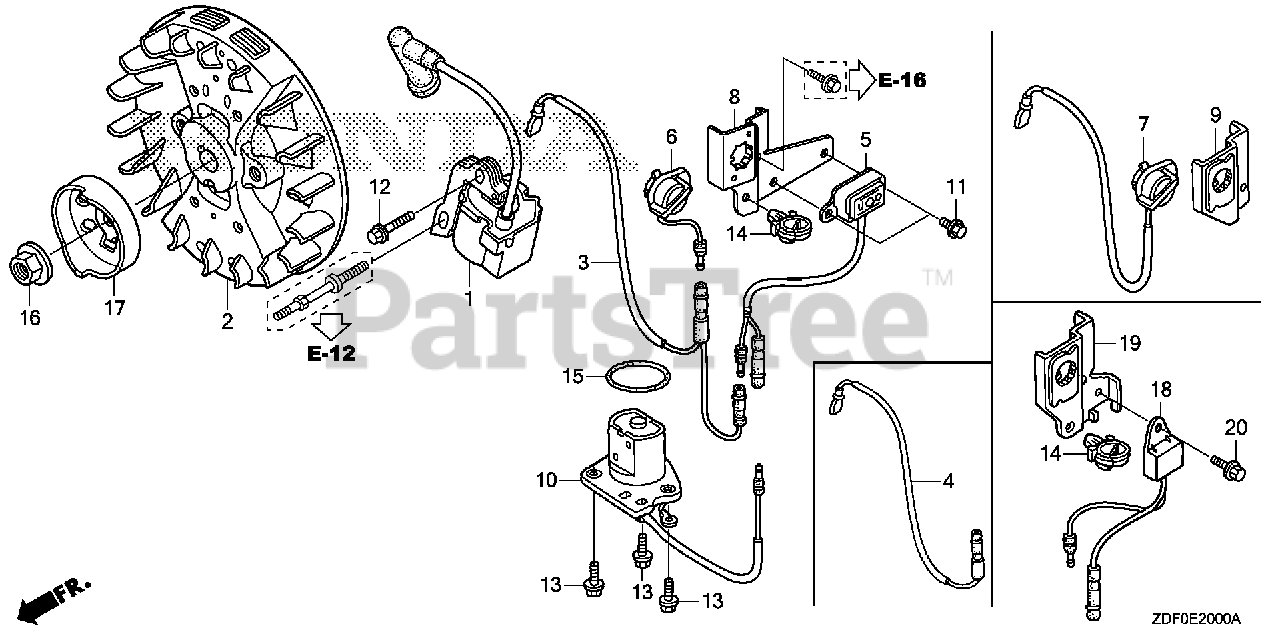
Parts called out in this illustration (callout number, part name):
1	COIL ASSY., IGNITION
3	WIRE, STOP SWITCH
6	SWITCH ASSY., ENGINE STOP
6	SWITCH ASSY., ENGINE STOP (TOYO DENSO)
10	SWITCH ASSY., OIL LEVEL
12	BOLT, FLANGE (5X20)
13	BOLT, FLANGE (5X14)
14	CLIP, WIRE HARNESS
15	O-RING (34.6X2.5)
16	NUT, FLANGE (10MM)
17	PULLEY, RECOIL STARTER
18	ALERT UNIT, OIL
19	BRACKET, STOP SWITCH
20	BOLT, FLANGE (6X8)
